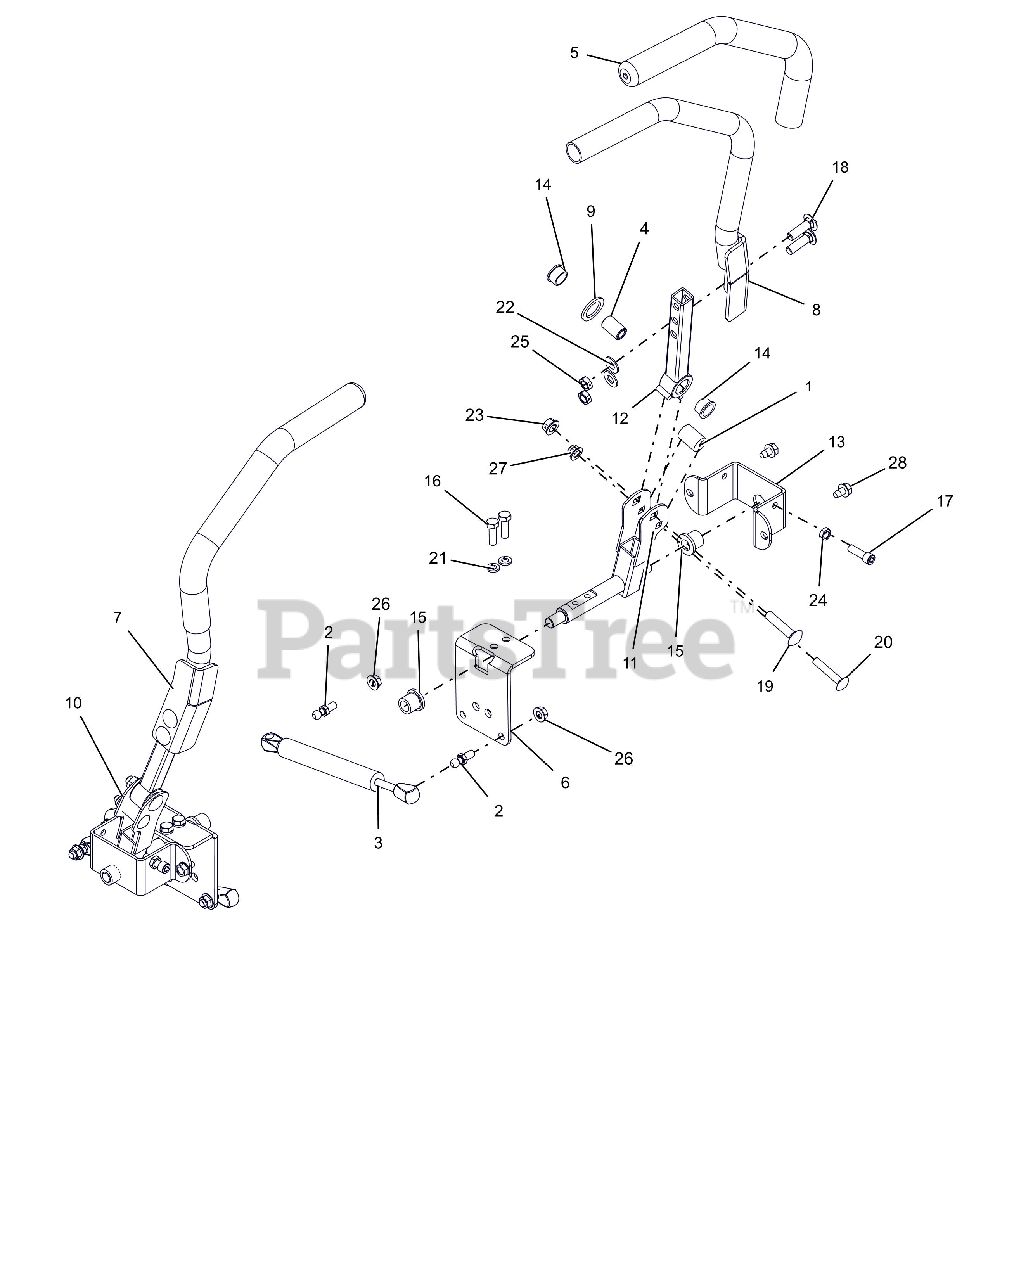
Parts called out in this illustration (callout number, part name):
1	BSHG,ECCEN .328X.750X1.01 PM
2	STUD- BALL
3	DAMPER, STABILUS
4	SPACER, .375X.625X.970 (PM)
5	GRIP, HANDLEBAR 15" FOAM
6	BRKT, STEEERING
7	WLDMT, STEERING HANDLE RH
8	WLDMT, STEERING HANDLE LH
9	WASHER, FRICTION .875X1.25X.10
10	WLDMT,STEERING ARM LOWER RIGHT
11	WLDMT,STEERING ARM LOWER LEFT
12	WLDMT, UPPER CONTROL ARM
13	BRKT, STEERING
14	BSHG-FLG, .625X.75X.450X.875
15	BSHG-FLG .515X.750X.745X1.00NY
16	BLT-HEX .31-18X1.00 GR8 YWZC
17	SCR, SKH .312-18X1.00 G8 SS
18	BLT,RHSSN .38-16X1.25 G5 BFP
19	BLT,RHSSN .38-16X1.75 G5 BFP
20	BLT,RHSSN .31-18X1.75 G5 BFP
21	@WSHR-LK .31X.078 REG YWZC
22	@WSHR-FL-STL.406X.812X.065 YWZ
23	NUT-LK-CTR-FLG .38-16 YWZC
24	NUT- JAM .312-18 YWZC
25	@NUT-LK-CTR-JAM .375-16 YWZC
26	@NUT-LK-TOP-FLG .31-18 YWZC
27	@NUT-LK-NYL-FLG .31-18 YWZC
28	@SCR-TAP .31-18X.50 HWH TR YWZ
